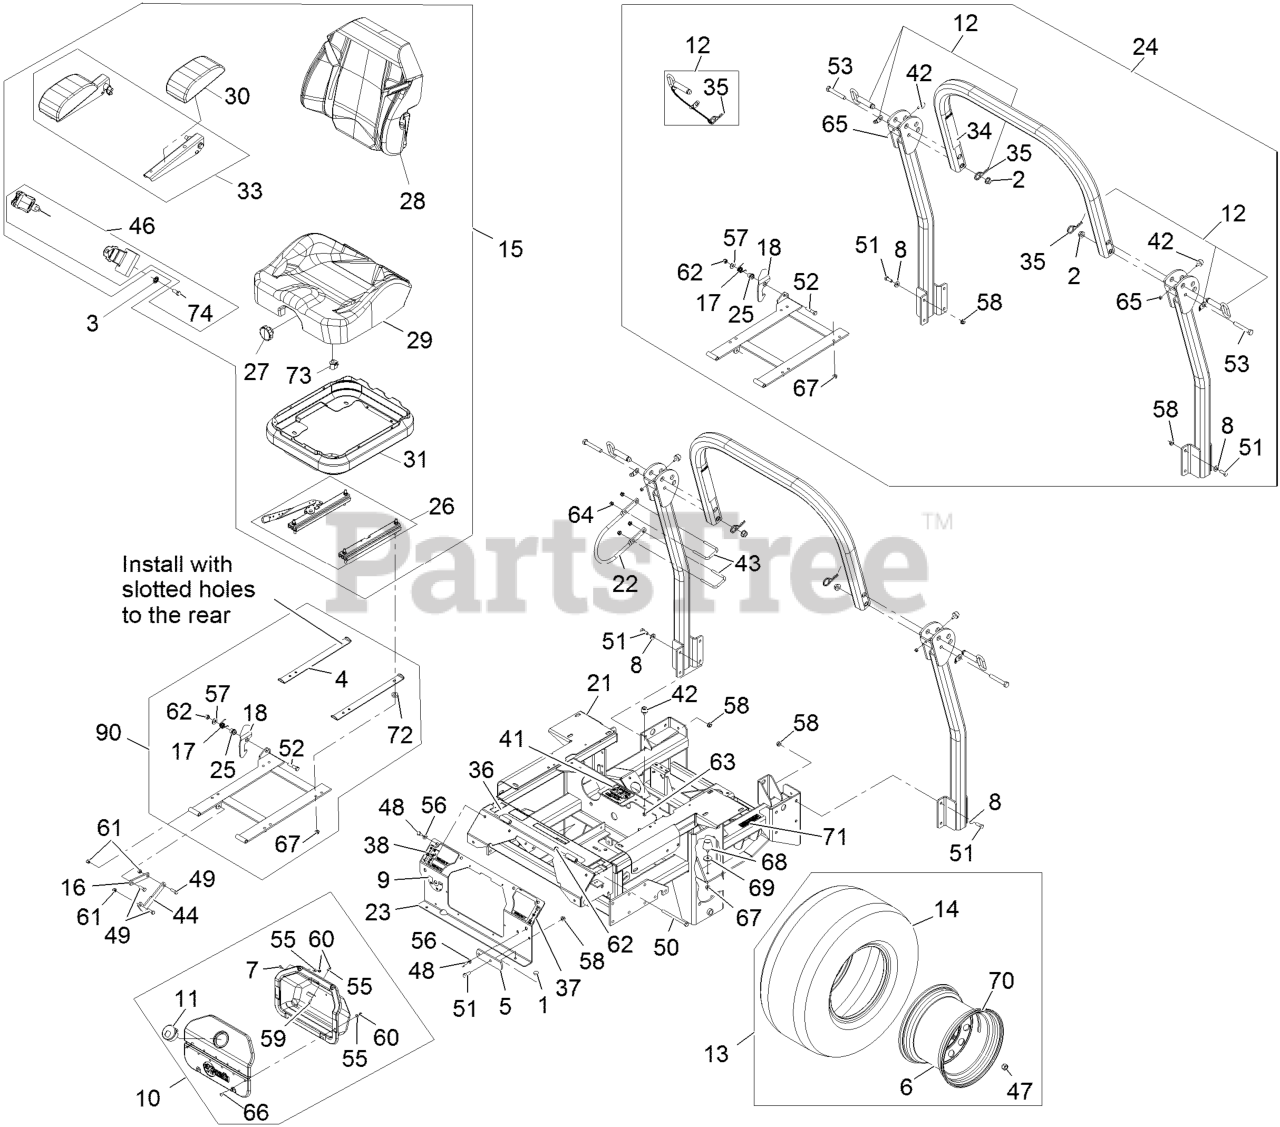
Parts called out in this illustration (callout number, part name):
3	WASHER-SPRING
4	STOP/SPACER-SEAT
5	STOP-BRAKE, PARK
7	SCREW-HEAD, TRUSS
8	WASHER-BELLEVILLE
9	DECAL-VALVE, FUEL
10	ASM,CUBBY
11	LATCH,CUBBY
12	PIN-FOLD, ROPS
13	WHEEL AND TIRE ASM
16	LINK-STOP, SEAT
17	SPRING-TORSION, LATCH
18	CATCH-LATCH, SINGLE
21	ASM,KDXS ENGINE DECK W/DE
23	ASM, CONSOLE W/DECALS
24	KIT, 06 XS ROPS
25	BUSHING-LATCH, SEAT
26	SEAT TRACK SET
27	KNOB-ADJUSTER
28	COVER-BACK 310951VN476
29	COVER-CUSHION 310952VN476
30	ARM REST PAD SET
31	COVER-SUSPENSION, BELLOWS
33	ARM REST SET
34	DECAL-WARNING, FOLDING RO
35	HAIRPIN
36	DECAL-CONSOLE, TOP
37	DECAL,PARK BRAKE
38	DECAL,DECK HEIGHT
41	DECAL,WARNING
42	BUMPER-RUBBER
44	LINK-STOP, SEAT
46	SEAT BELT KIT
47	NUT-LUG
48	SCREW-HH
49	SCREW-HH
50	SCREW-HH
51	SCREW-HH
52	SCREW-HH
53	SCREW-HH
55	WASHER-FLAT
56	WASHER-PLAIN
57	WASHER-FLAT
58	NUT-HHF, WHIZ
59	SCREW-PPH
60	NUT-LOCK, NI
61	NUT-LOCK, NI
62	NUT-LOCK, NI
63	NUT-LOCK, NI
64	NUT-LOCK, NI
65	NUT-LOCK, NI
68	Bumper-Rubber
71	DECAL-ARRESTER, SPARK
73	SWITCH-BAIL
74	SCREW-HH
90	KIT,SEAT FRAME SERVICE
